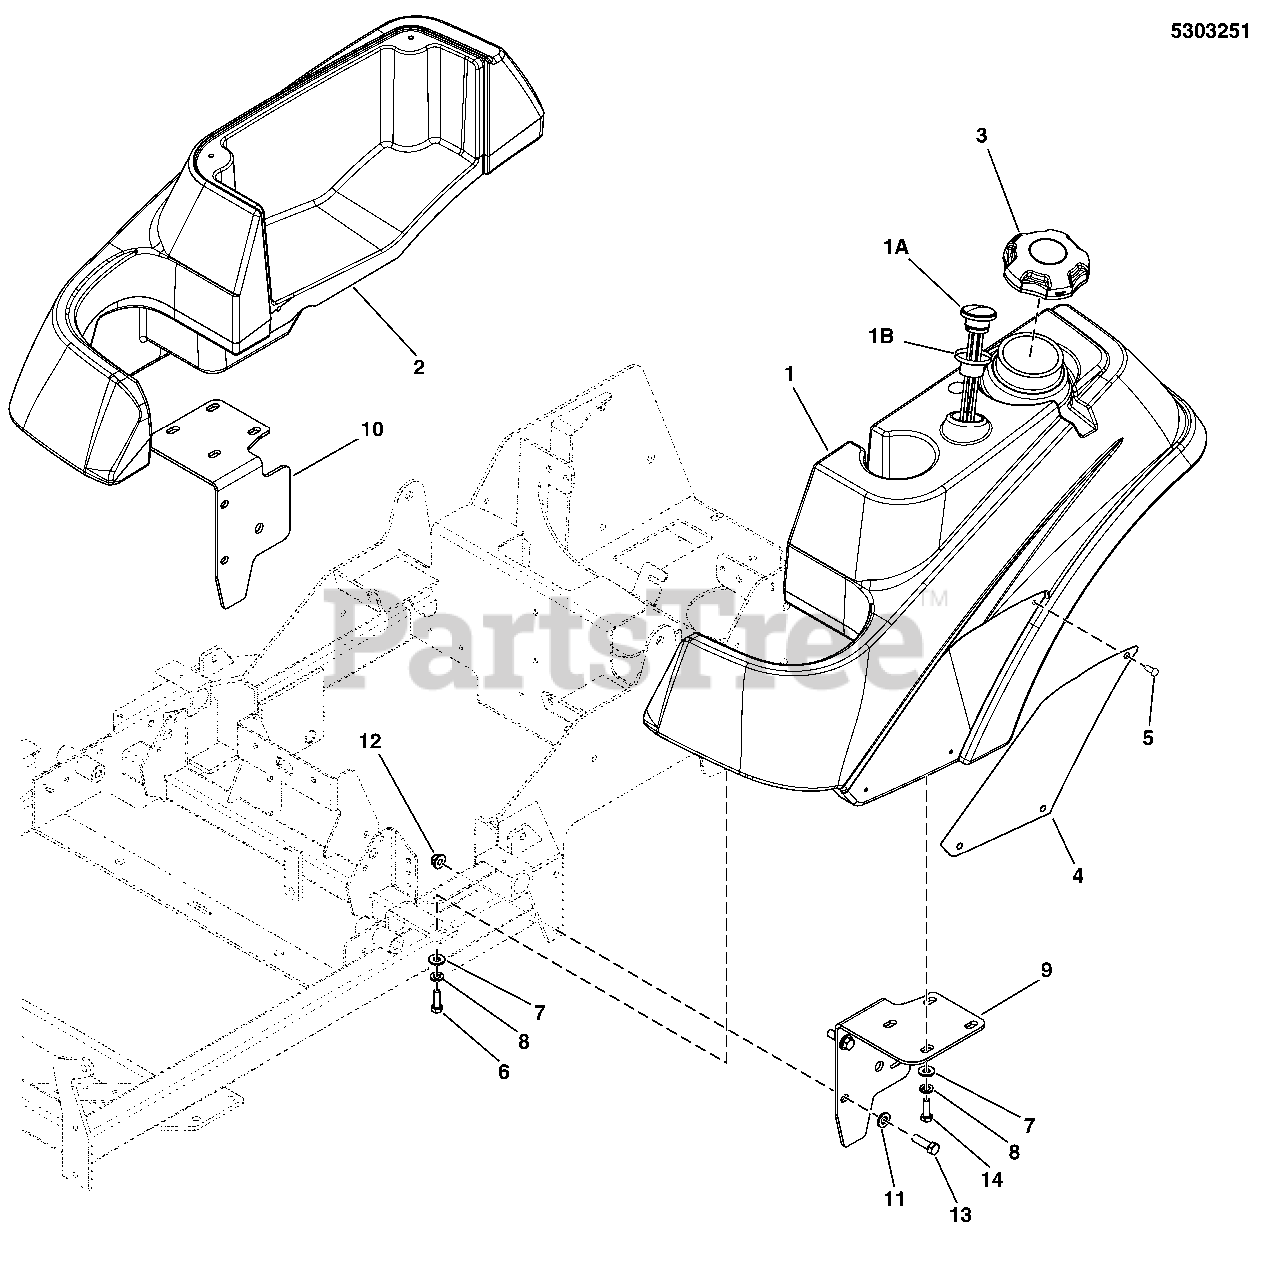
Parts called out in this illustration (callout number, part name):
1	TANK, FUEL, IS500 & IS1500 - LH
1A	FUEL GAUGE, 12"
1B	GROMMET, FUEL GAUGE
2	TANK, FENDER, 1500Z - RH
3	FUEL CAP, 3-1/2", MANAGED VENT OUT, 12"
4	BADGE, CITATION, ORANGE
5	SCREW, #10-24 X 3/8 ALLEN BHBZ
6	BOLT, 5/16-18 X 1 GD5 YZ
7	WASHER, 5/16 F436 FLAT
8	WASHER, 5/16 LOCK YZ
9	WELD, TANK MOUNT, LH, IS600 - BLK
10	WELD, TANK MOUNT, RH, IS600 - BLK
11	WASHER, 3/8 GD.9 FLAT
12	NUT, 3/8-16 HEX NYLOCK FLANGE
13	BOLT, 3/8-16 X 1-1/4 GD5
14	BOLT, 5/16-18 X 3/4 GD5 YZ
